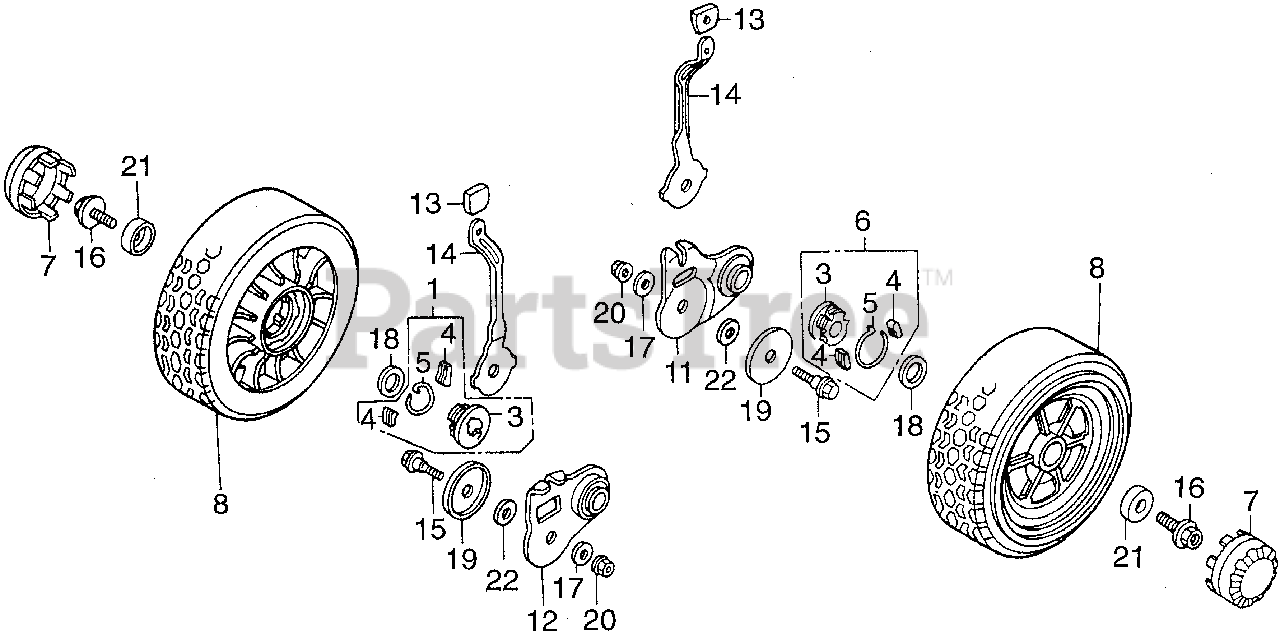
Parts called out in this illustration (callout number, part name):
1	HOLDER, R. RATCHET
3	HOLDER, RATCHET
4	RATCHET
5	SPRING, RATCHET RETURN
6	HOLDER, L. RATCHET
7	CAP, WHEEL
8	WHEEL, PROPELLED (8") (NH31)
10	TIRE (8 INCH)
11	ARM C, WHEEL ADJUSTER (NOT AVAILABLE)
12	ARM D, WHEEL ADJUSTER (NOT AVAILABLE)
13	GRIP, ADJUSTER
14	PLATE, RR. ADJUSTING (NOT AVAILABLE)
15	BOLT, ADJUSTING CENTER
16	BOLT, WHEEL
17	WASHER A, HANDLE HOLDER SETTING
18	WASHER (16MM)
19	WASHER, WHEEL
20	NUT, FLANGE (8MM)
21	WASHER B, PIVOT
22	SEAL, RR. WHEEL
